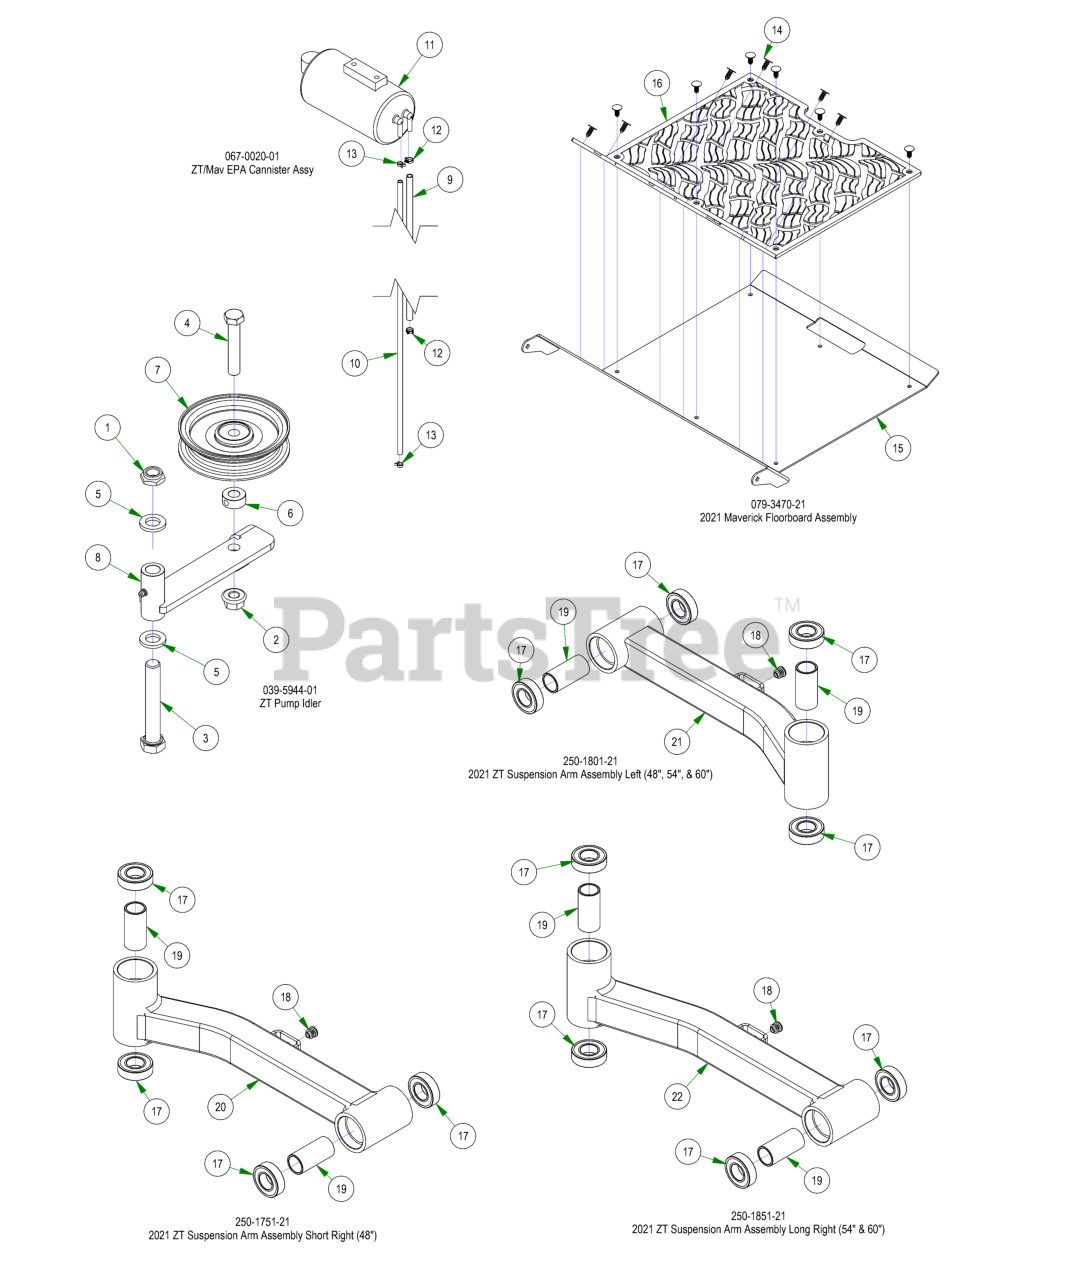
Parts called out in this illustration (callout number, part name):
1	5/8-11 NYLON INSERT JAM LOCKNUT ZINC
2	1/2-13 NYLON INSERT FLANGE LOCKNUT ZINC
3	5/8-11 X 4 HEX CAP SCREW (GR.8) ZINC YELLOW
4	1/2-13 X 2-3/4 HEX CAP SCREW (GR.5) ZINC
5	.635 ID X 1.120 OD X .140 THICK FLAT WASHER NYLON
6	1/2 SOLID SHAFT COLLAR (W/1 SET SCREW) ZINC
7	4 3/4" Idler Pulley
8	Pump Idler Bracket
9	1/4" Vinyl Tubing, 46" Long
10	3/16" Vinyl Tubing, 55" Long
11	Carbon Canister
12	3/16 Vinyl Clamp
13	3/16" Vinyl Hose Clamp
14	Ratchet Fastener
15	2018 Maverick Floorboard
16	2021 Maverick Floor Mat W/ Reaper Tread
17	1641 BEARING W/2 CONTACT RUBBER SEALS
18	5/8 Round Insert
19	2016 Front Bearing Spacer
20	2021 ZT RH Front Arm - Short
21	2021 ZT LH Front Arm
22	2021 ZT RH Front Arm - Long
